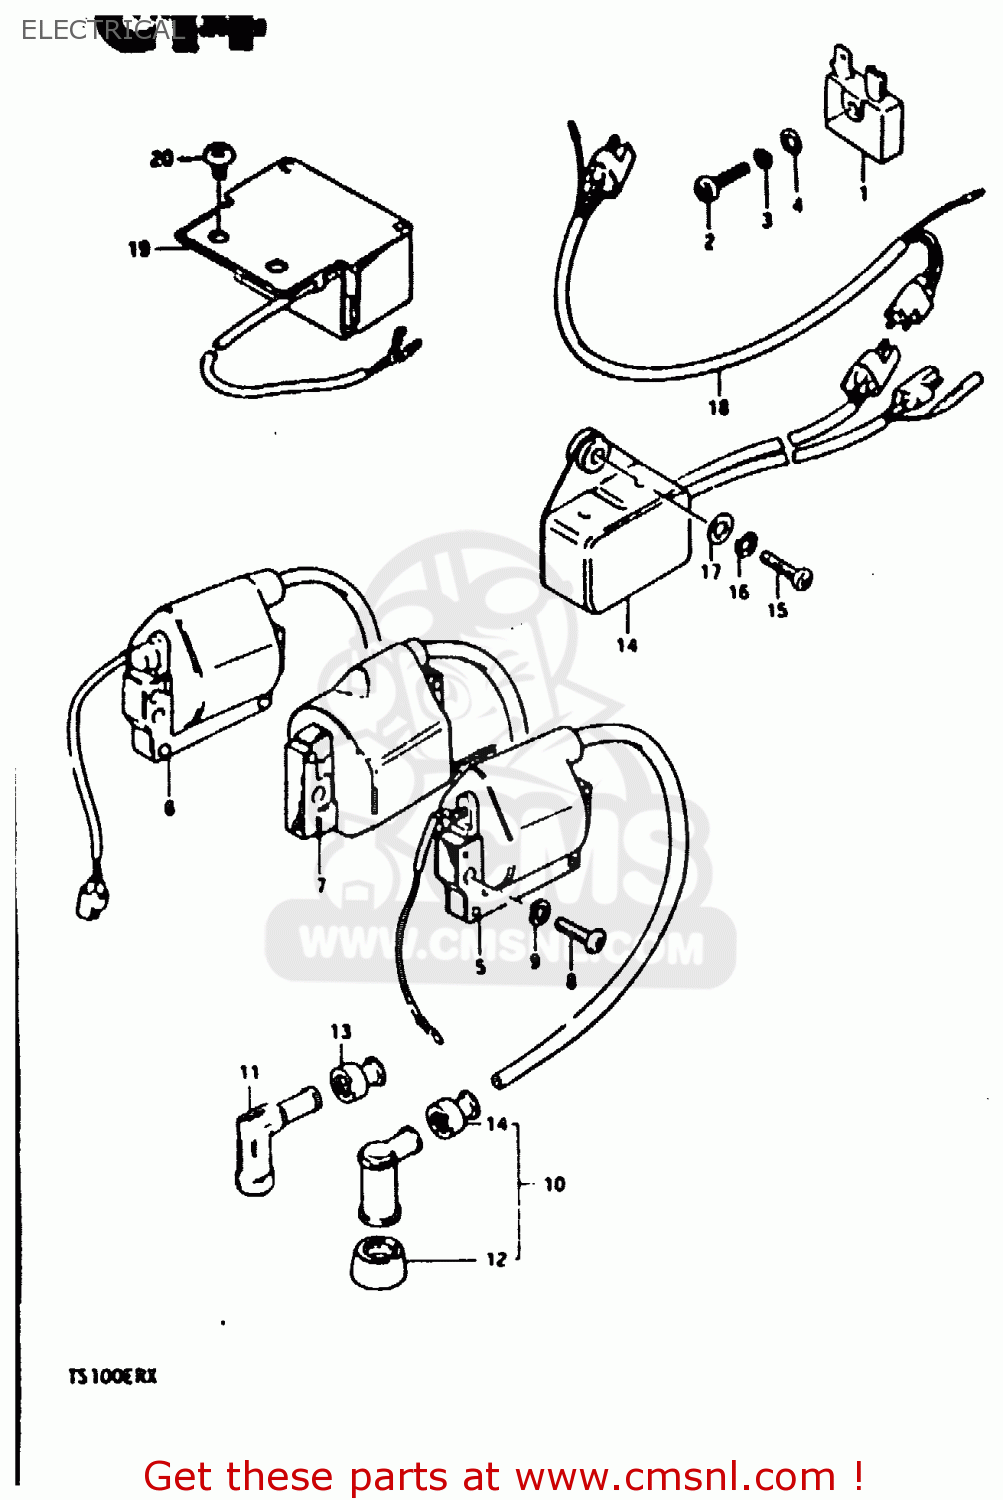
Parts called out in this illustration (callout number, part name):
1	RECTIFIER ASSEMBLY
2	SCREW 5X20
3	LOCK WASHER
4	WASHER
5	COIL ASSEMBLY,IGNITION
8	SCREW
9	LOCK WASHER
11	CAP,SPARK PLUG
13	SEAL,SPARK PLU
19	RESISTOR ASSY
20	SCREW
